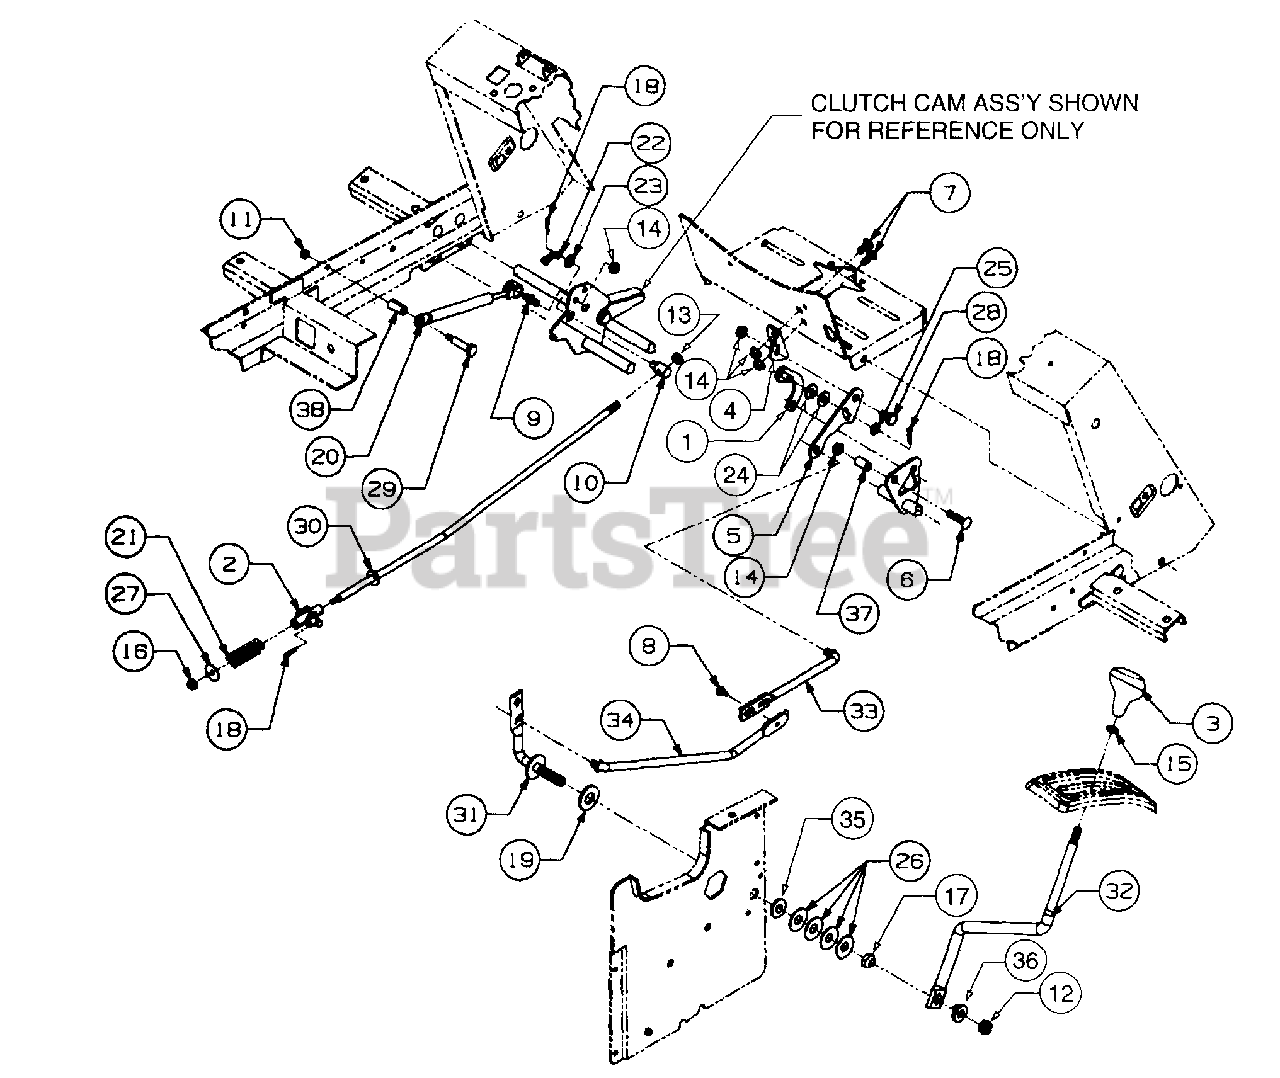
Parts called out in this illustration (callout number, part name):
1	Bracket, Cruise Return
2	Pivot Assy, Sleeve
3	Knob, Shifter
6	Bolt, Carriage, 5/16-18 x 1.5
7	Bolt, Carriage, 5/16-18 x .75
8	Screw, Hex Wash Hd Tap 1/4-20 x .50
9	Screw, Ball, 5/16-18
10	Ferrule, Adjustment
11	Nut, Hex Sems, 1/4-20
12	Nut, Hex Top Lock, 1/2-20
13	Nut, Hex Jam, 3/8-24 GR5
14	Nut, Hex Flange Lock, 5/16-18
15	Nut, Hex Jam, 3/8-16 GR5
16	Nut, Hex Flange Lock, 1/4-20
17	Nut, Hex, 1/2-20
18	Pin, Internal Cotter
19	Washer Friction
20	Cylinder, Damper
21	Spring, Compression, .63 ID x 2.0
22	Spring, Extension, .38 OD x 1.44
23	Washer, Flat, .406 x .75 x .063
24	Washer, Flat, .375 x .870 x .090
25	Washer, Flat, 5/16
26	Washer, Bell
27	Washer, Flat, .265 x 1.0 x .03 Hd
28	Bolt, Shoulder, .437 Dia x .180 Lg
29	Bolt, Shoulder, .347 Dia x 1.375
30	Rod, Hydro Adjustment
31	Rod, Shift
32	Rod, Gear Selector
33	Link, Front Hydro Shifter
34	Link, Rear Hydro Shifter
35	Bushing, Shoulder
36	Hub, Shift
37	Spacer, .377 ID x .50 OD x .830
38	Spacer Tubing .375 x .52 x 1.04
